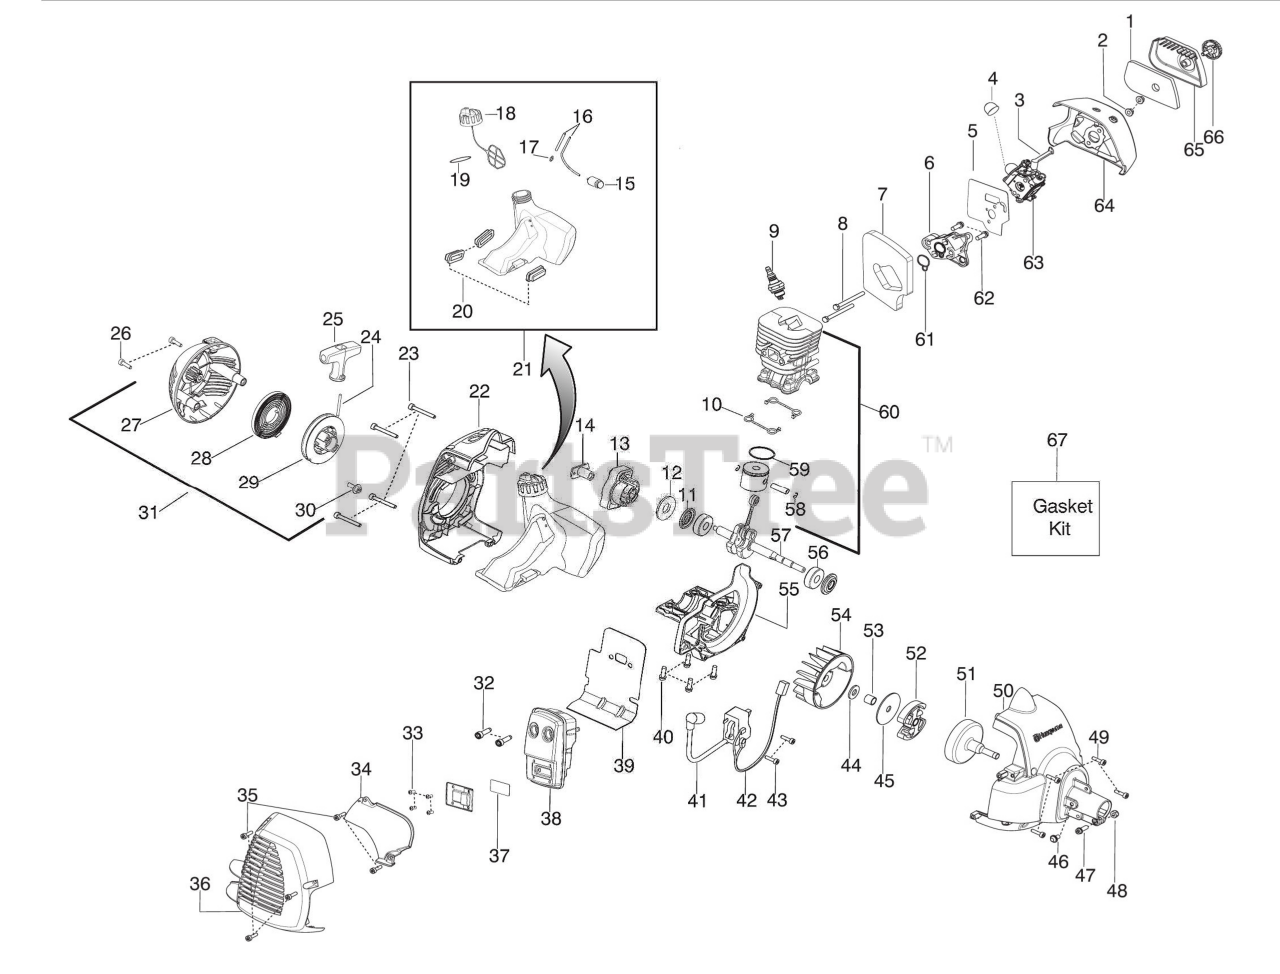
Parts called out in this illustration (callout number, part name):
2	Nut - Carb. Screw
3	Lever - Choke
4	Bulb - Purge
5	Kit-Carb. Gasket
6	Adaptor - Carb.
7	Foam - Gasket
9	Plug - Spark (RCJ-6Y)
10	Seal - Cylinder
11	Seal - Crankshaft
12	Washer
13	Assy - Starter Cup
14	Coupling - Starter
15	Assy - Fuel Filter
16	Kit - Fuel Line
17	Fitting - Fuel Line
18	Assy - Cap w/ret.
19	O-Ring - Fuel Cap
20	Isolator - Fuel Tank
21	Kit - Fuel Tank
22	Shroud - Rear
24	Kit - Rope
25	Handle - Starter
27	Starter Hsg. w/eyelet
28	Kit - Starter Spring
29	Kit - Starter Pulley
31	Assy-Starter Hsg.
32	Bolt - Muffler
33	Screw
34	Shield - Heat
36	Guard - Muffler
37	Kit - Spark
38	Kit - Muffler
39	Gasket-Paper Met.
41	Module
42	Assy - Leadwire
45	Washer - Clutch
50	Assy - Fan Housing
51	Assy - Clutch Drum
52	Kit - Clutch Assy.
55	Crankcase - cast
57	Crankshaft - Assy
58	Retainer - Piston Pin
59	Ring - Piston
60	Kit - Cyl./Piston
61	Seal - adaptor
62	Screw
63	Kit – Carb.
64	Airbox
65	Cover - Air Box
66	Assy - Knob
67	Kit - Gasket
